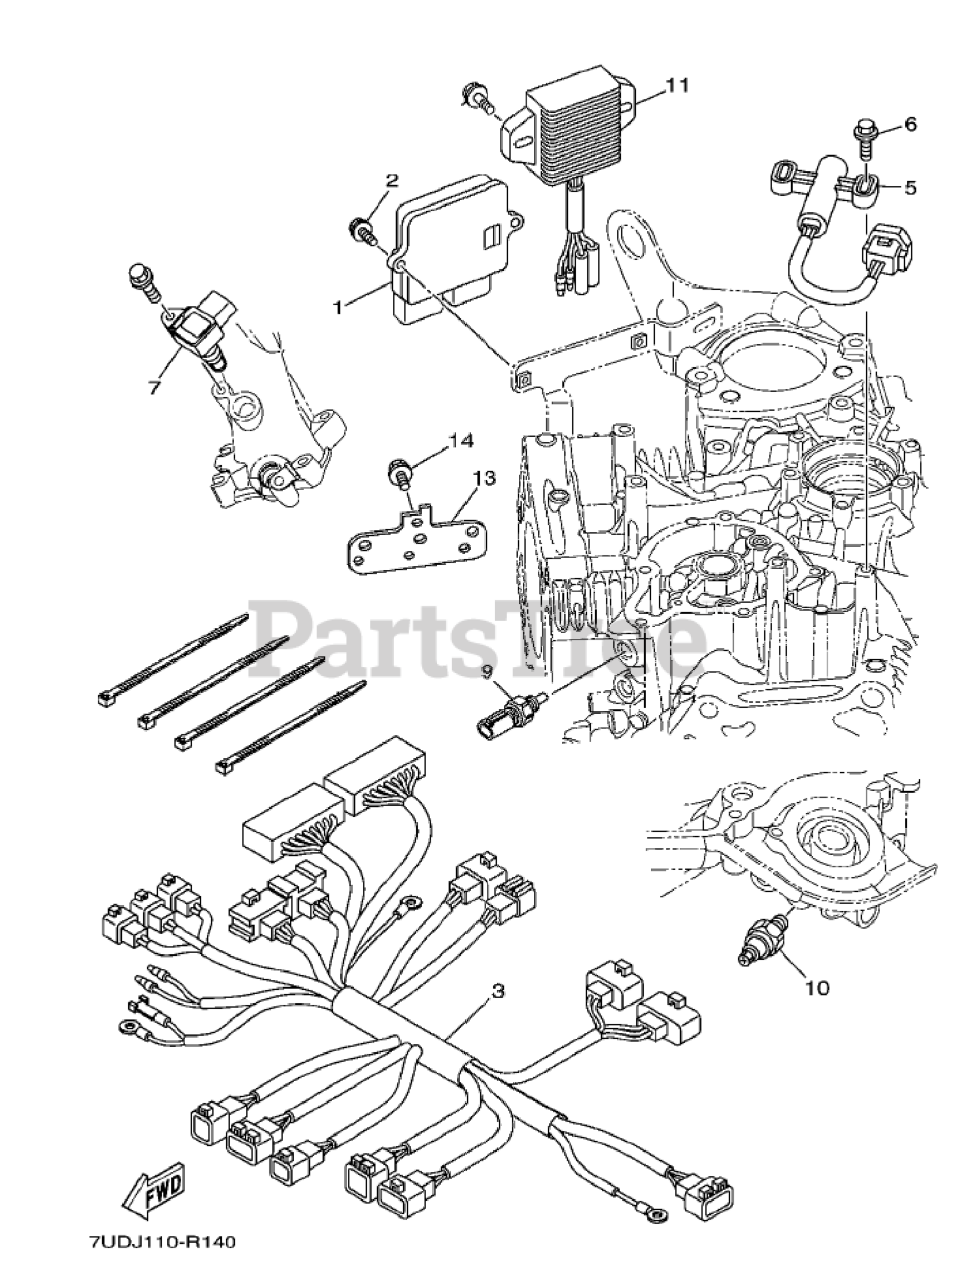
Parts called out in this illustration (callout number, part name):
1	CONTROL UNIT ENGINE YAMAHA PN:
2	BOLT YAMAHA PN: 90105-05804
3	WIRE LEAD YAMAHA PN: 7UD-H1115
5	SENSOR CRANK POSITION YAMAHA P
6	BOLT YAMAHA PN: 95802-06020
7	SENSOR T-MAP YAMAHA PN: 7UD-H2
9	SENSOR OIL TEMP YAMAHA PN: 7UD
10	SWITCH OIL PRESSURE ASSY YAMAH
11	REGULATOR AND RECTIFIER ASSY Y
13	STAY 1 YAMAHA PN: 7UD-E2637-00
14	BOLT YAMAHA PN: 95802-06010
